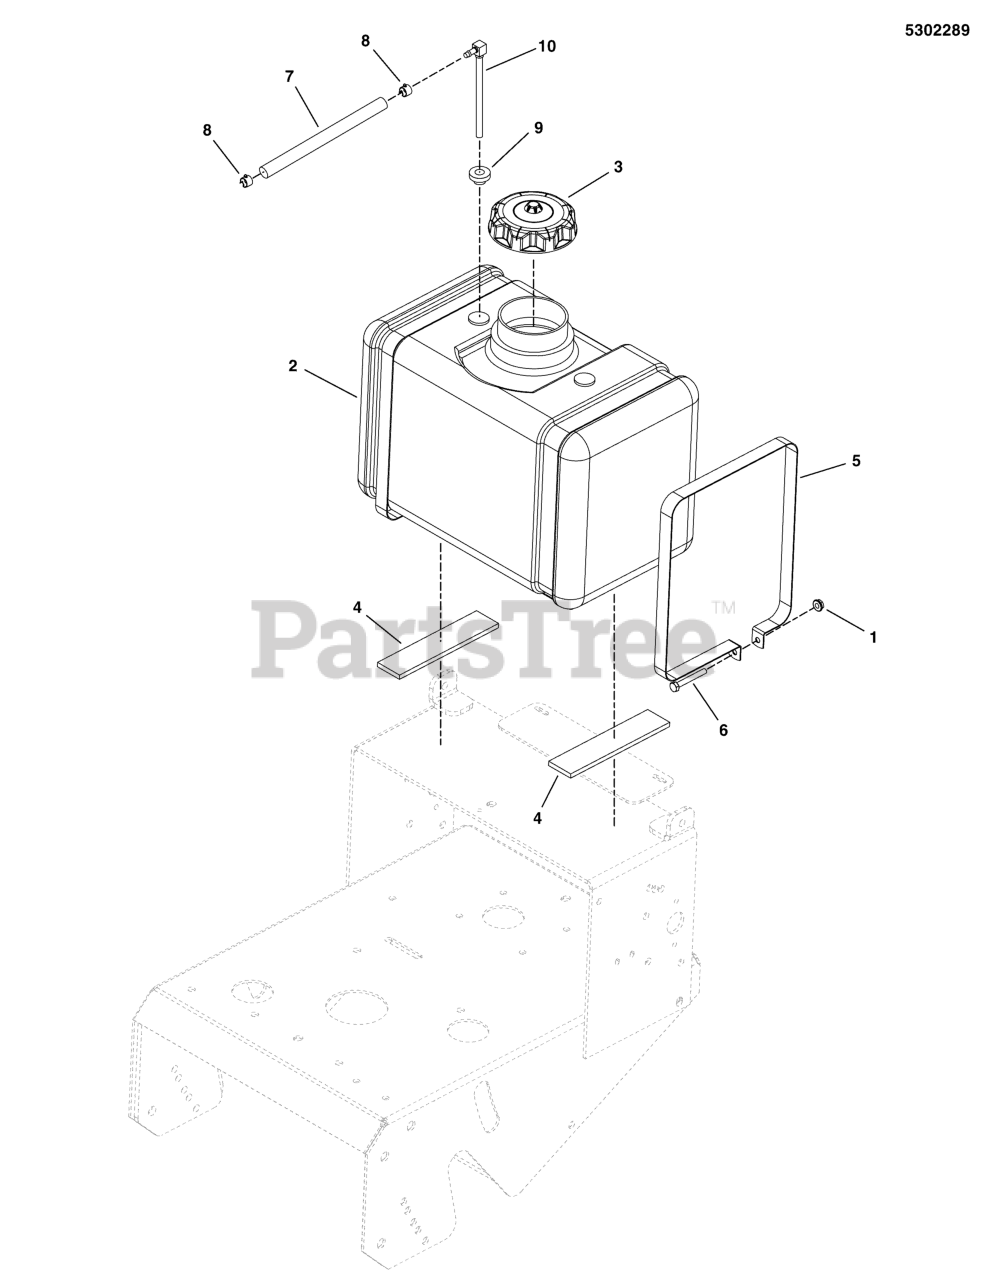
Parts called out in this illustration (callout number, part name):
1	NUT, 1/4-20 HEX SERR. FLANGE
2	TANK, 5 GAL, W DROP TUBE/VENT
3	FUEL CAP, 3-1/2", MANAGED VENT OUT, 12"
4	PAD, RUBBER MOUNT
5	STRAP, FUEL TANK
6	BOLT, 1/4-20 X 1-1/4, GD5
8	CLAMP, HOSE, EXTERNAL, 1/2 - RED
9	BUSHING-FUEL TANK RED RUBBER
10	PICKUP TUBE ASM, FUEL TANK, 8.0" (SV)
11	GROMMET
